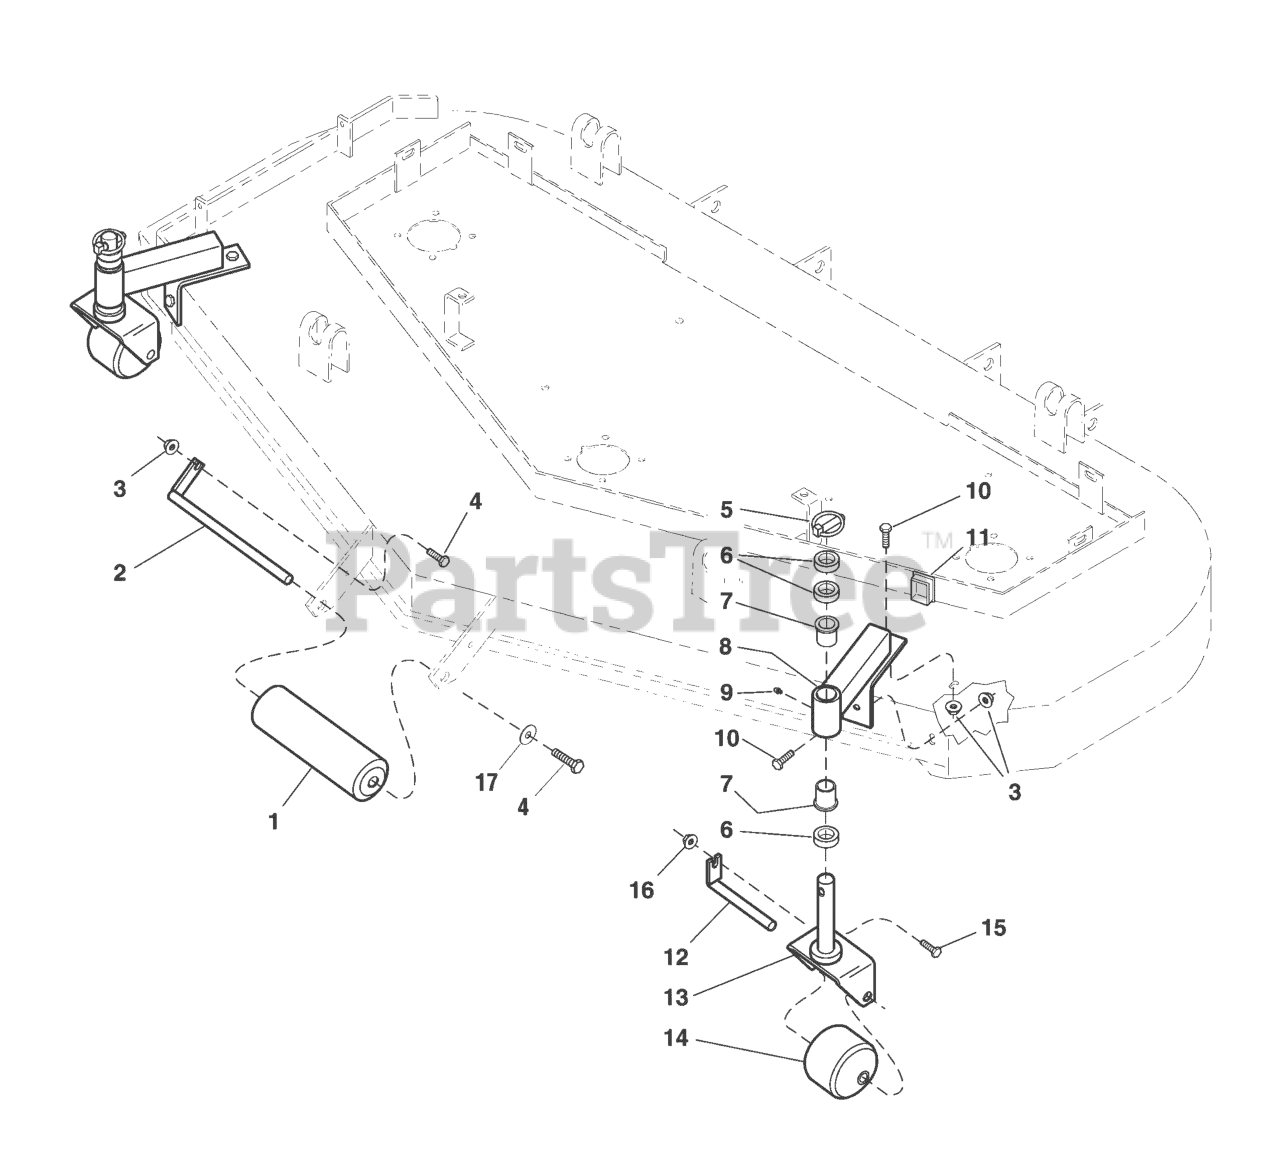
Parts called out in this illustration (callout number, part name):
1	ROLLER
3	NUT, 3/8-16 Hex Serrated Flange
4	BOLT, 3/8-16 X 1" GD5 CZ
5	PIN, Lynch
6	SPACER, 1.02 x 1.56 x .50
7	BUSHING, FLANGE
8	CASTER MOUNT ARM
9	GREASE FITTING
10	BOLT, 3/8-16 X 3/4" GD5 CZ
11	CAP, Plastic
12	CASTER ROLLER PIN
13	CASTER YOKE
14	ROLLER, Caster
15	BOLT, 5/16-18 X 3/4 GD5
16	NUT, 5/16-18 HEX SERRATED FLANGE (SMALL)
17	WASHER, .390 X 1.50 X .109 YZ
